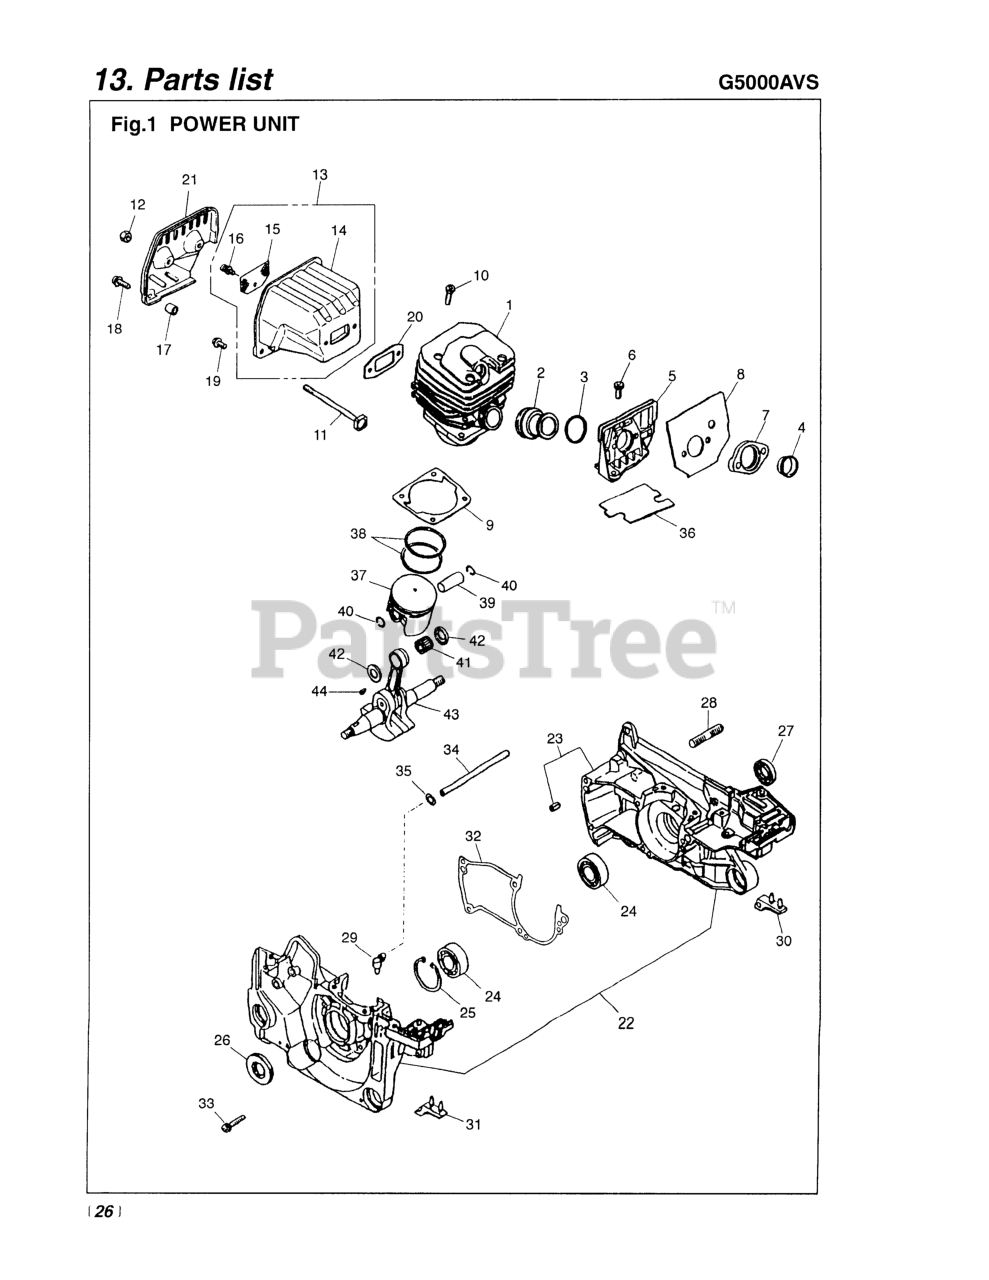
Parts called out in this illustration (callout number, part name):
1	CYLINDER
2	PIPE
3	SPRING
4	GUIDE
6	SCREW (REPLACES 2616-24320)
8	GASKET (RPLS 2880-14360)
9	GASKET, CYLINDER (RPLS -14210)
11	BOLT
12	NUT, MUFFLER (RPLS 3356-15230
13	MUFFLER ASSY (RPLS -15102)
15	ARRESTER, SPARK
19	SCREW
20	GASKET
21	COVER
22	CRANKCASE ASSY
24	BEARING (REPLACES 2810-21240)
25	RING, SNAP, M35 X 1.5
26	SEAL, OIL
27	SEAL, OIL
28	BOLT
30	STOPPER, REAR (RPLS 2670-22510
31	STOPPER, REAR
36	MAT (RPLS 2810-22410)
37	PISTON
38	PISTON RING
39	PIN, PISTON
40	RING, SNAP
41	BEARING
42	WASHER, THRUST
44	KEY
